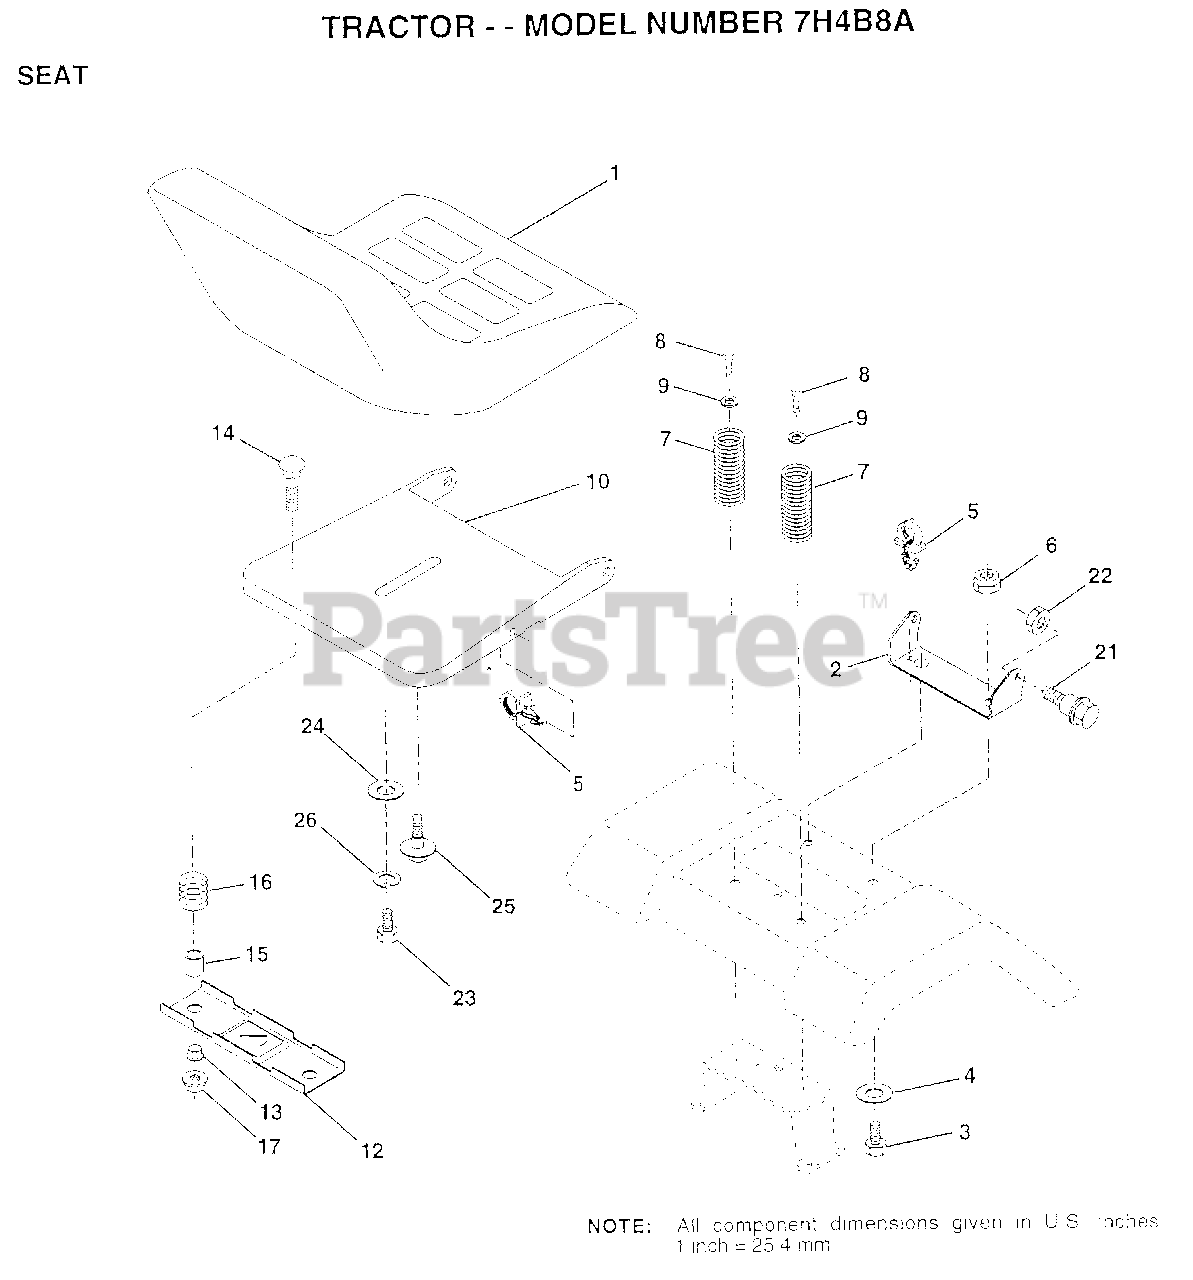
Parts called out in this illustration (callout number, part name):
2	BRACKET PVT SEAT
3	BOLT
4	WASHER PM
5	CLIP.PUSH-IN.HING
6	NUT
7	SPRING COMPRESSIO
8	SCREW GTV
9	WASHER
12	BRKT SWITCH
13	BUSHING
15	SPLIT SPACER
16	SPRING
21	"BOLT,SHOULDER"
22	NUT
23	BOLT
24	WASHER
25	"BOLT,SHOULDER"
26	LOCKWASHER
